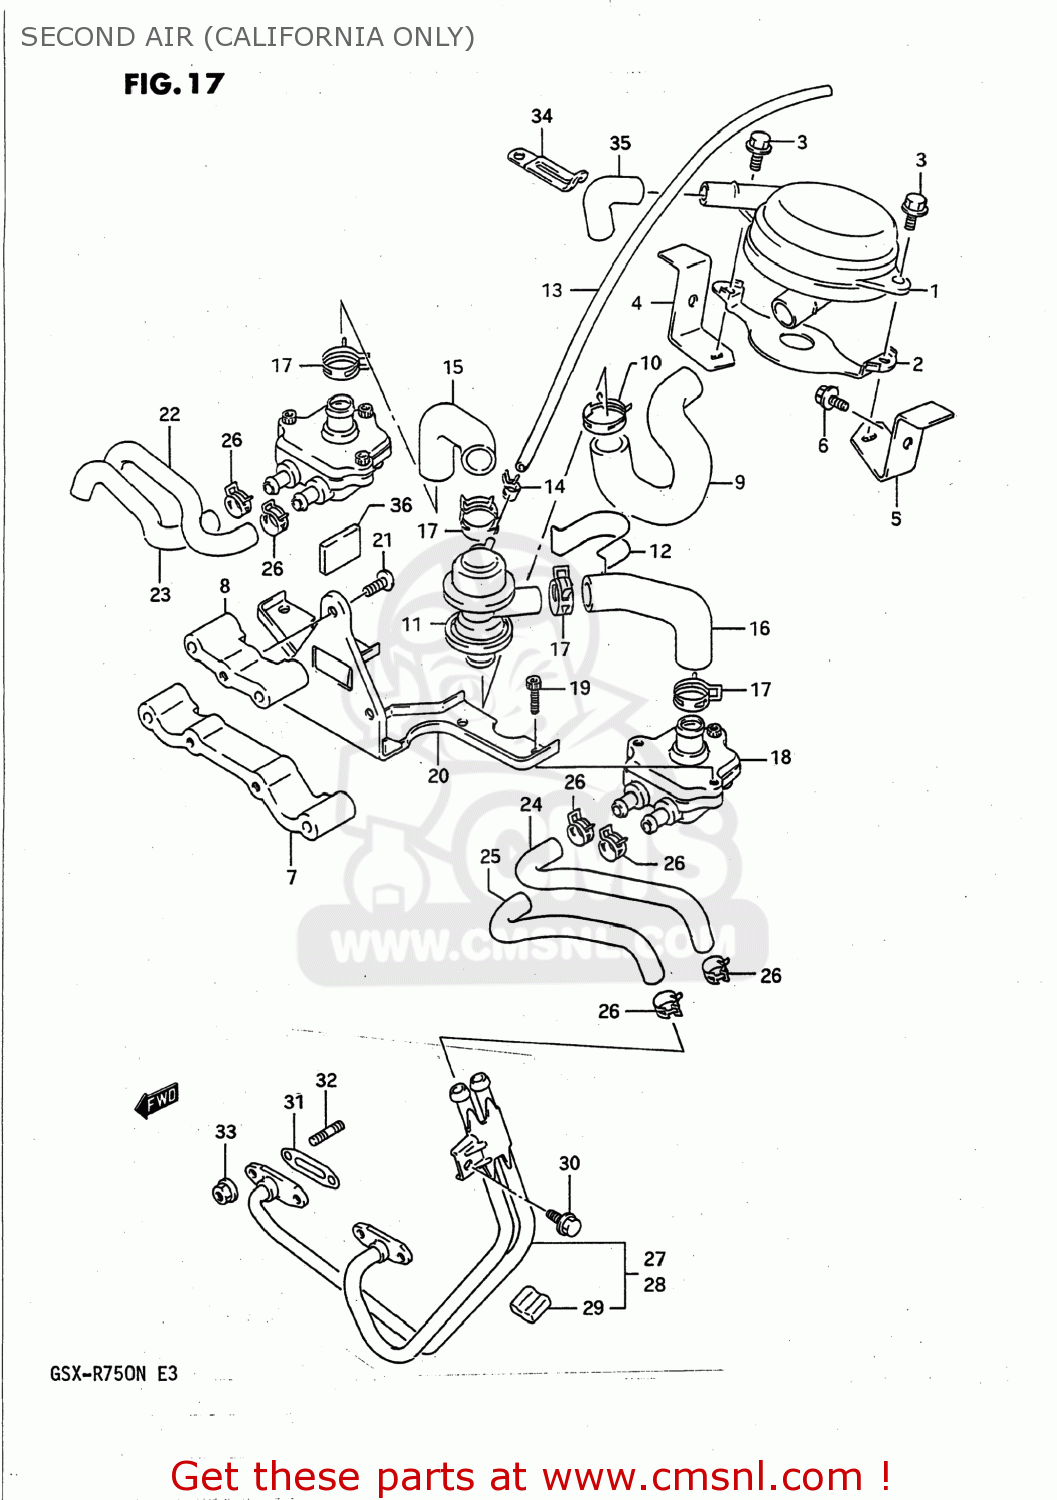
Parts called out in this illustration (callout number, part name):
1	CLEANER ASSEMBLY,SECOND AIR
2	HOLDER,SECOND AIR CLEANER
3	BOLT
4	BRACKET,SECOND AIR CLEANER
5	BRACKET,SECOND AIR CLEANER
6	BOLT
7	SPACER,SECOND AIR BRACKET,LOWER
8	SPACER,SECOND AIR BRACKET,UPPER
9	HOSE,SECOND AIR NO.3
10	CLIP
11	VALVE ASSEMBLY,AIR SWITCH
12	CLAMP,SWITCHING VALVE
13	HOSE
14	CLAMP
15	HOSE,SECOND AIR NO.2,RIGHT
16	HOSE,SECOND AIR NO.2,LEFT
17	CLIP
18	VALVE ASSY,2ND AIR REED
19	BOLT
20	BRACKET,SECOND AIR VALVE
21	SCREW
22	HOSE,SECOND AIR NO.1,RIGHT,INLET
23	HOSE,SECOND AIR NO.1,RIGHT,OUTLET
24	HOSE,SECOND AIR NO.1,LEFT,INLET
25	HOSE,SECOND AIR NO.1,LEFT,OUTLET
26	CLIP
27	PIPE,SECOND AIR,RIGHT
28	PIPE,SECOND AIR,LEFT
29	(CA) CUSHION
30	BOLT 6X12
31	GASKET,SECOND AIR PIPE (NAS)
32	STUD BOLT
33	NUT 6MM
34	CLAMP L:35
35	(CA) HOSE,SECOND AIR CLEANER
36	CUSHION
